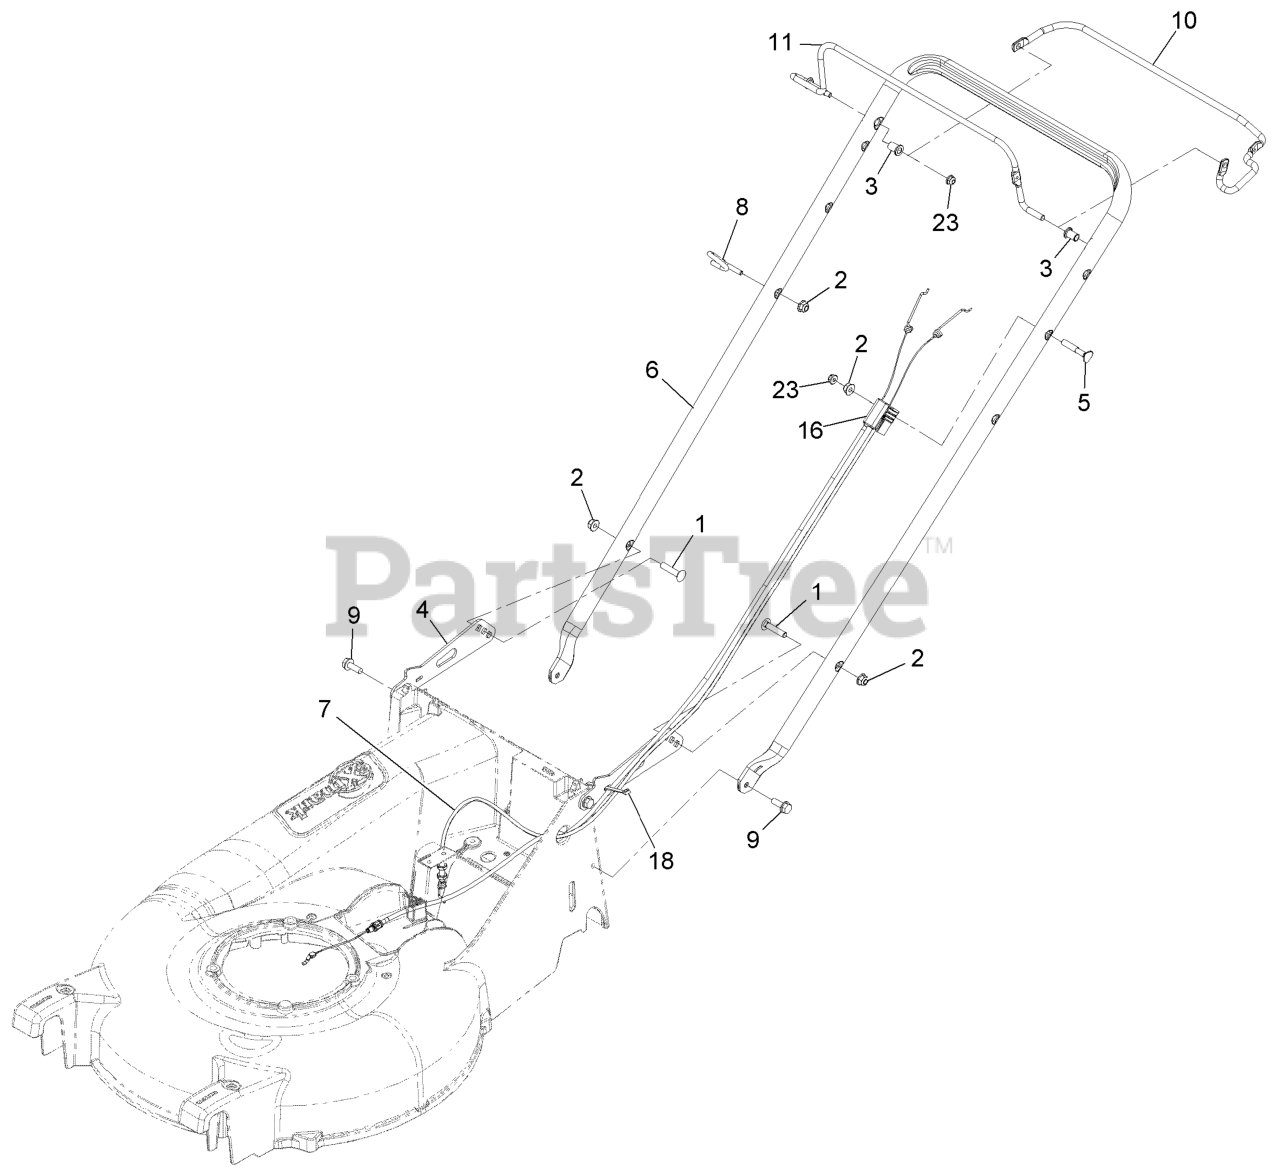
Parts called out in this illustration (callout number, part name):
1	BOLT-CARR
2	NUT-HF, NI
3	BUSHING-HANDLEBAR
4	BRACKET,HANDLEBAR
6	HANDLEBAR-P21
8	GUIDE,ROPE
9	SCREW-TAPTITE
11	BAIL,OPC/BBC
16	CABLE-ZONE KAWASAKI
18	TIE-CABLE
